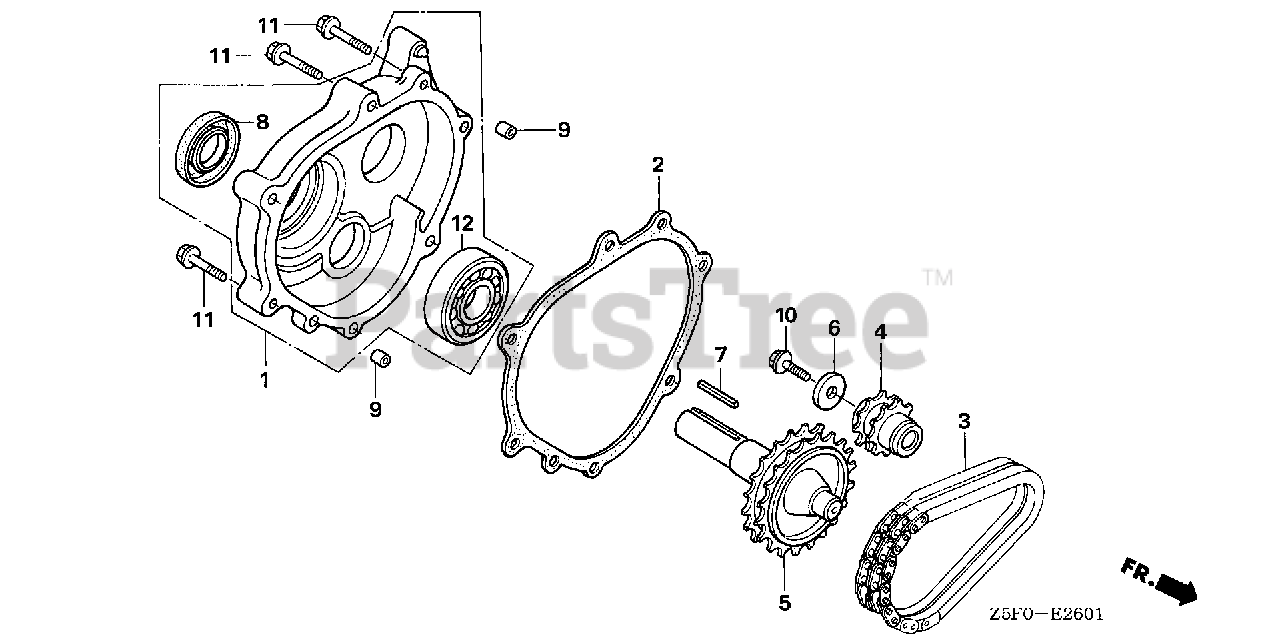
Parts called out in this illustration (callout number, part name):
1	COVER ASSY., CHAIN CASE
2	GASKET, CHAIN CASE COVER
3	CHAIN, P.T.O. DRIVE
4	SPROCKET, DRIVE (14T)
5	SHAFT, P.T.O. (28T)
6	WASHER (8MM)
7	KEY (7X7X33) (OVER SIZE) (YELLOW)
8	OIL SEAL (30X46X8)
9	PIN, DOWEL (8X14)
10	BOLT, FLANGE (8X25)
11	BOLT, FLANGE (8X40)
12	BEARING, RADIAL BALL (6206)
